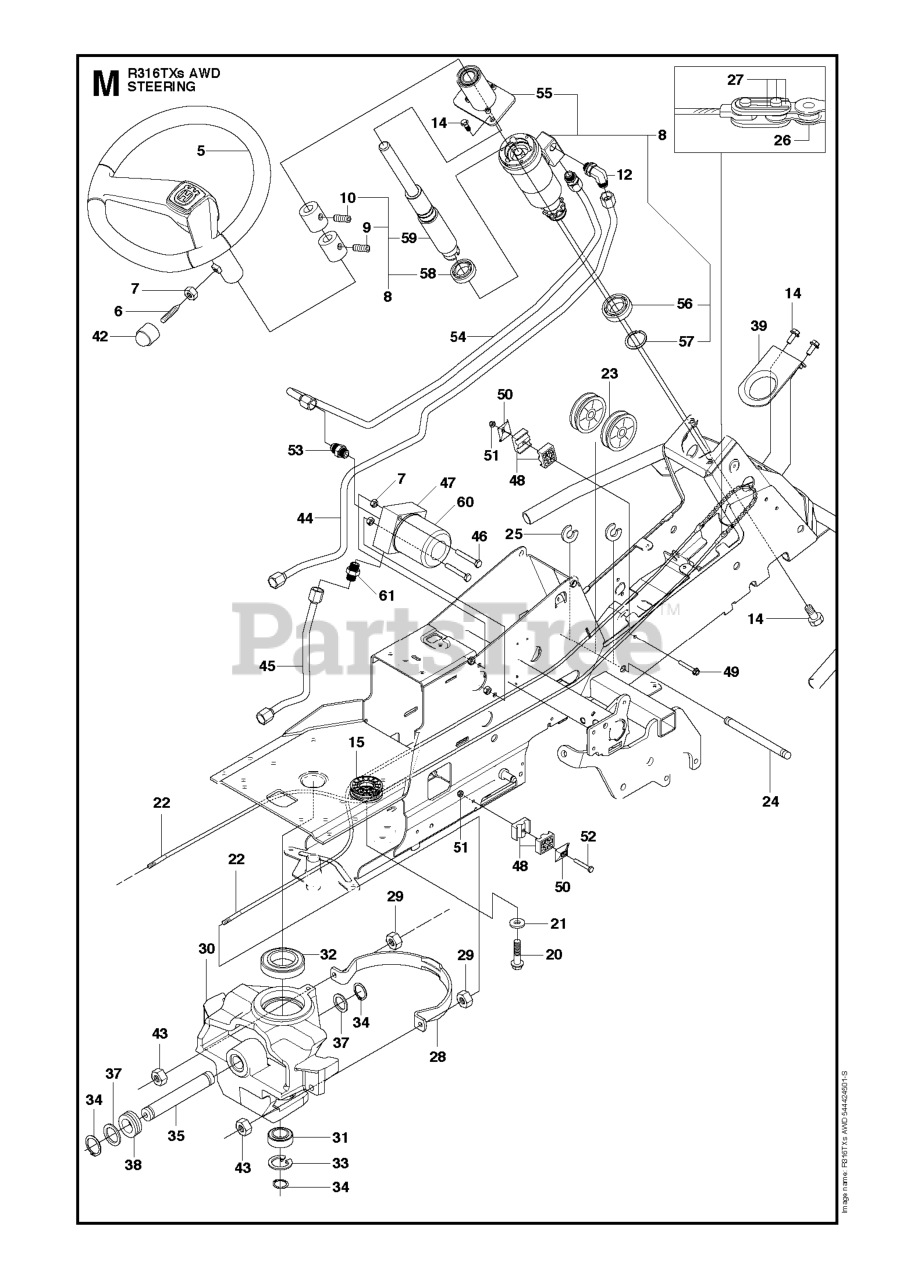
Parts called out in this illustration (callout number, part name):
5	STEERING WHEEL
7	NUT
9	SPACER
20	COLLAR SCREW
22	WIRE ASSY
25	RETAINING RING
28	WIRE GUIDE
29	NUT
31	Ball Bearing 6005-2rs
32	BALL BEARING 6010 2RS1
33	CIRCLIP SGH 47
34	RETAINING RING SGA 25
42	PROTECTIVE COVER
43	NUT
48	PIPE CLAMP
51	LOCKNUT M6
58	Ball Bearing 6005-2rs
60	FILTER
